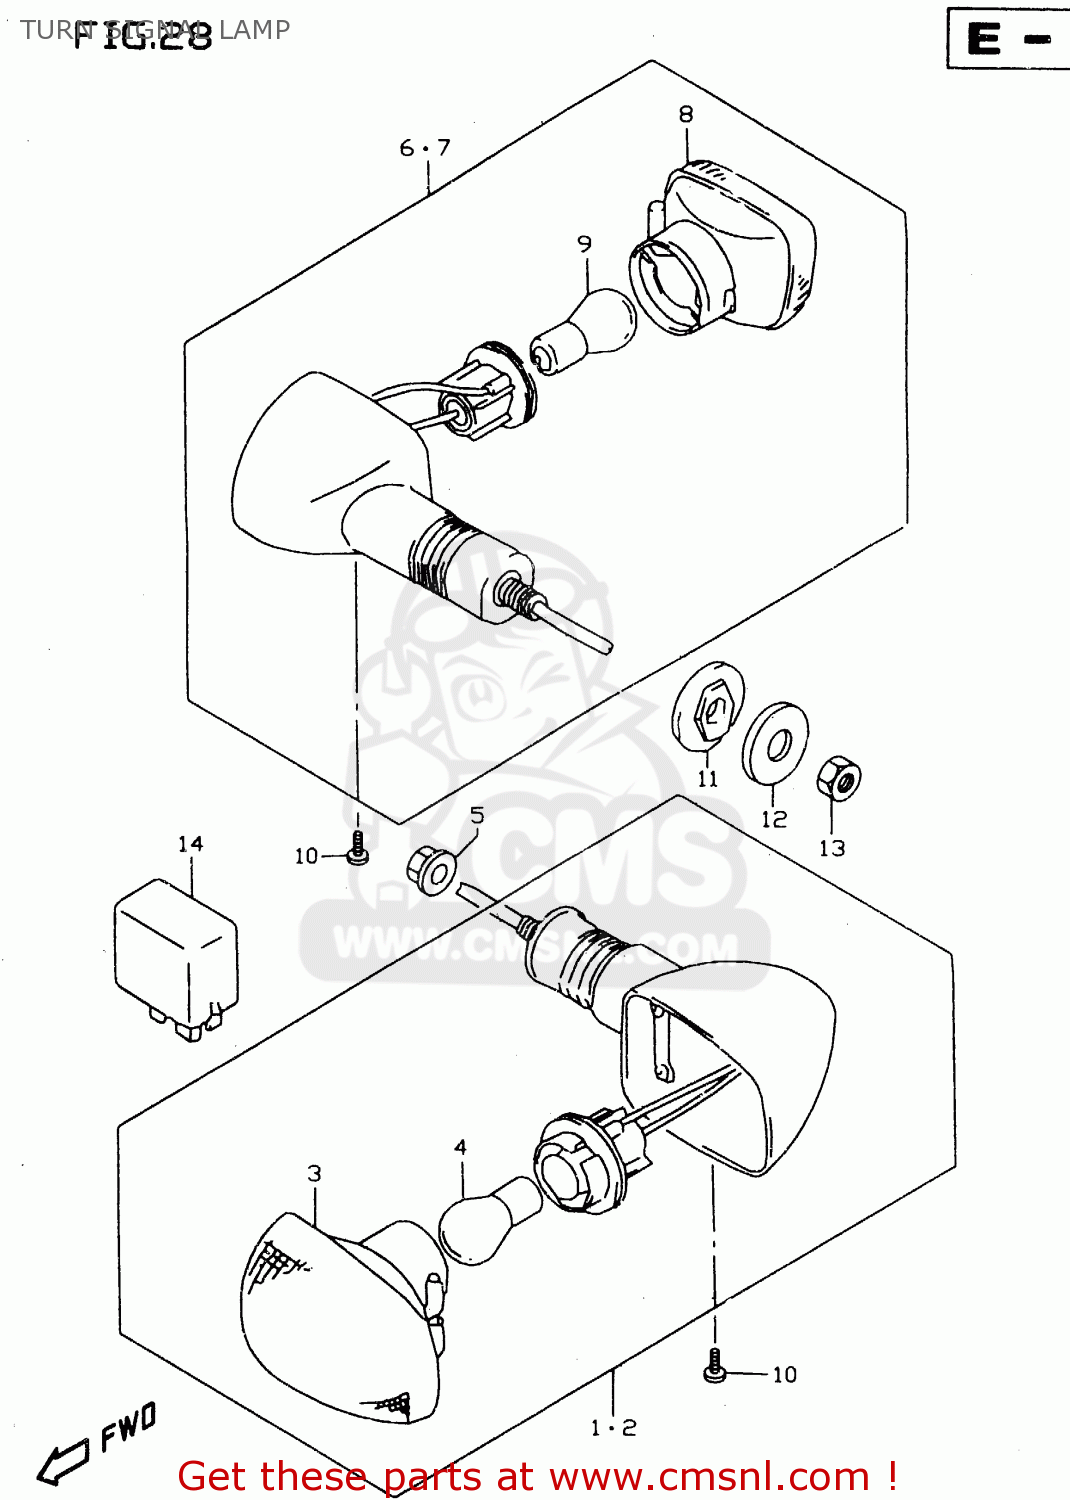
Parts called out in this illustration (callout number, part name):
1	LAMP,FR.TURN,R
2	LAMP,FR.TURN,L
3	LAMP UNIT
4	BULB(12V21W)
5	NUT
6	LAMP ASSY,RR TURNSIGNAL,R
7	LAMP ASSY,RR TURNSIGNAL,L
8	LAMP UNIT
9	BULB(12V21W)
10	SCREW
11	SPACER,RR TURNSIGNAL
12	WASHER(10.5X30X2.3)
13	NUT
14	RELAY ASSY,TURNSIGNAL LAMP
